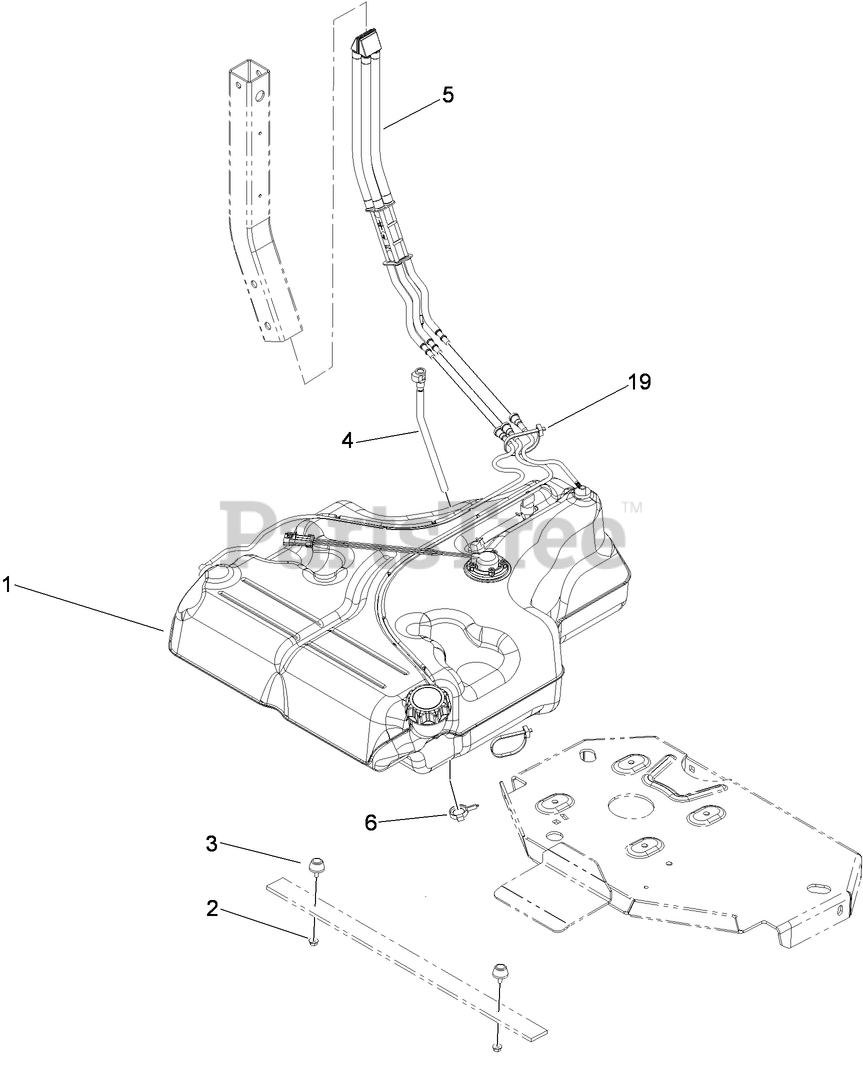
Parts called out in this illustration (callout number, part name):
1	FUEL TANK ASM
2	NUT-HF
3	BUMPER-RUBBER
4	TUBE-VENT, FUEL DRAIN
5	FUEL MANIFOLD VENT ASM
6	CLAMP-HOSE
19	TIE-PLASTIC
